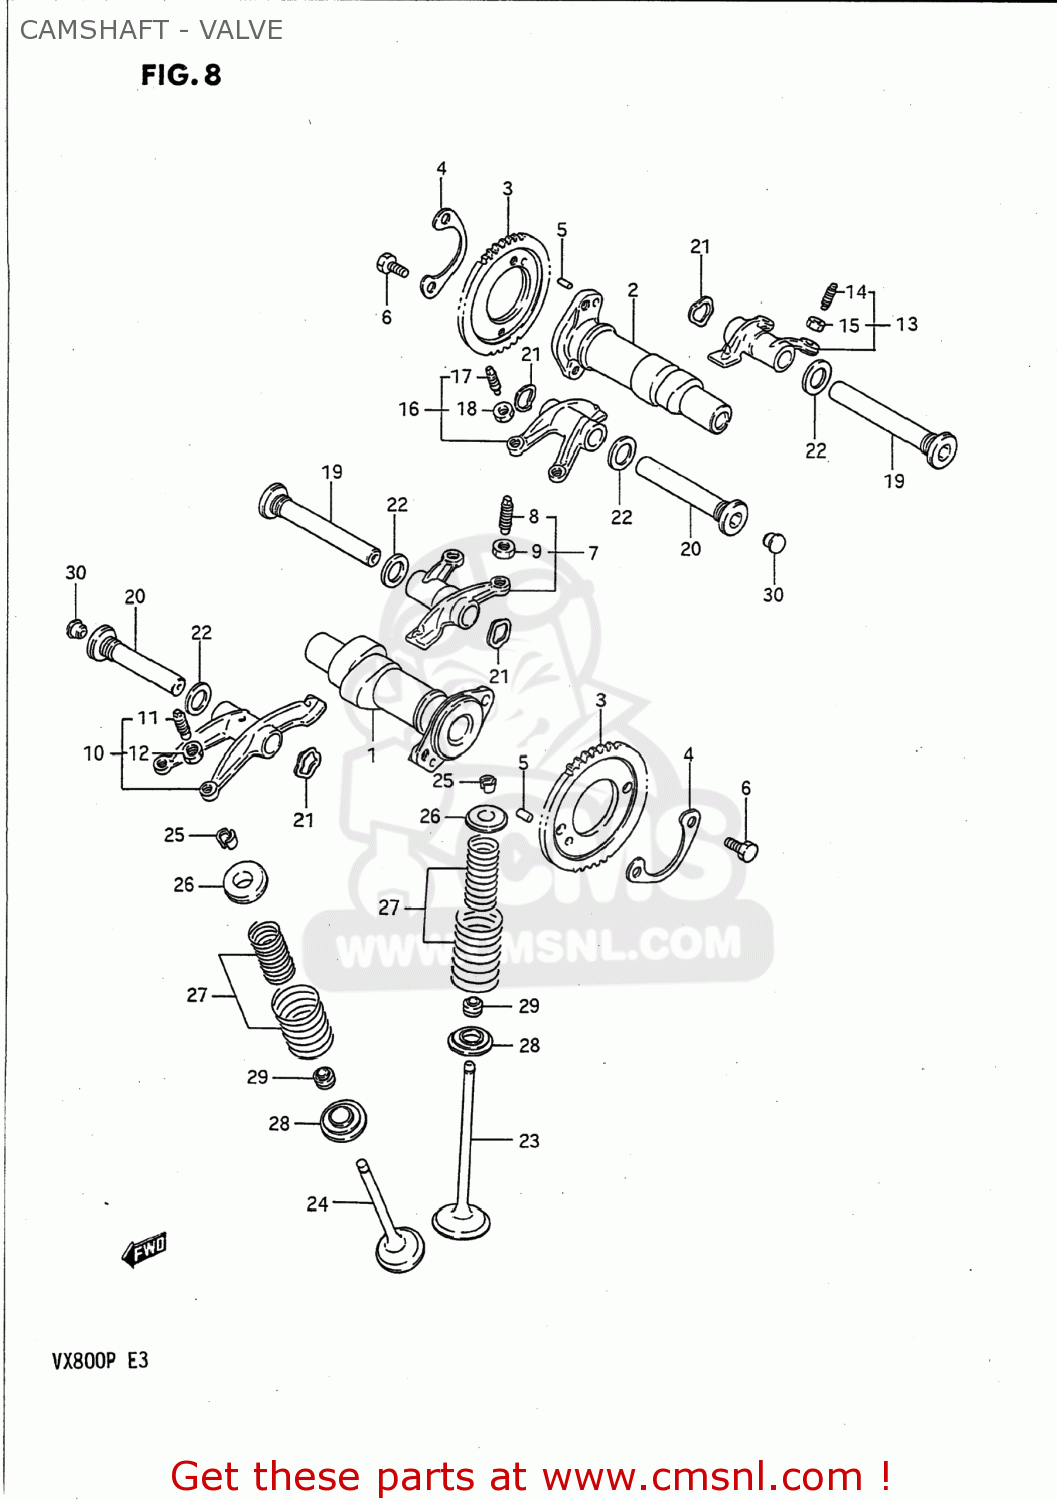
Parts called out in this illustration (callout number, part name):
1	CAMSHAFT,FR
2	CAMSHAFT,RR
3	SPROCKET,CAMSHAFT(NT:42)
4	WASHER,CAM CHAIN SPROCKET
5	PIN
6	BOLT(6X12.5)
7	ARM,INTAKE VALVE ROCKER FR
8	SCREW,TAPPET ADJUSTING
9	NUT,ADJUSTING SCREW
10	ARM,EXHAUST VALVE ROCKER FR
11	SCREW,TAPPET ADJUSTING
12	NUT,ADJUSTING SCREW
13	ARM,INTAKE VALVE ROCKER RR
14	SCREW,TAPPET ADJUSTING
15	NUT,ADJUSTING SCREW
16	ARM,EXHAUST VALVE ROCKER RR
17	SCREW,TAPPET ADJUSTING
18	NUT,ADJUSTING SCREW
19	SHAFT,VALVE ROCKER
20	SHAFT,VALVE ROCKER ARM
21	WASHER
22	GASKET(14X19.2X2) (NAS)
23	VALVE,INTAKE
24	VALVE,EXHAUST
25	COTTER,VALVE
26	RETAINER,VALVE SPRING
27	SPRING SET,VALVE
28	SEAT,VALVE SPRING
29	OIL SEAL
30	CAP(OD:12)
